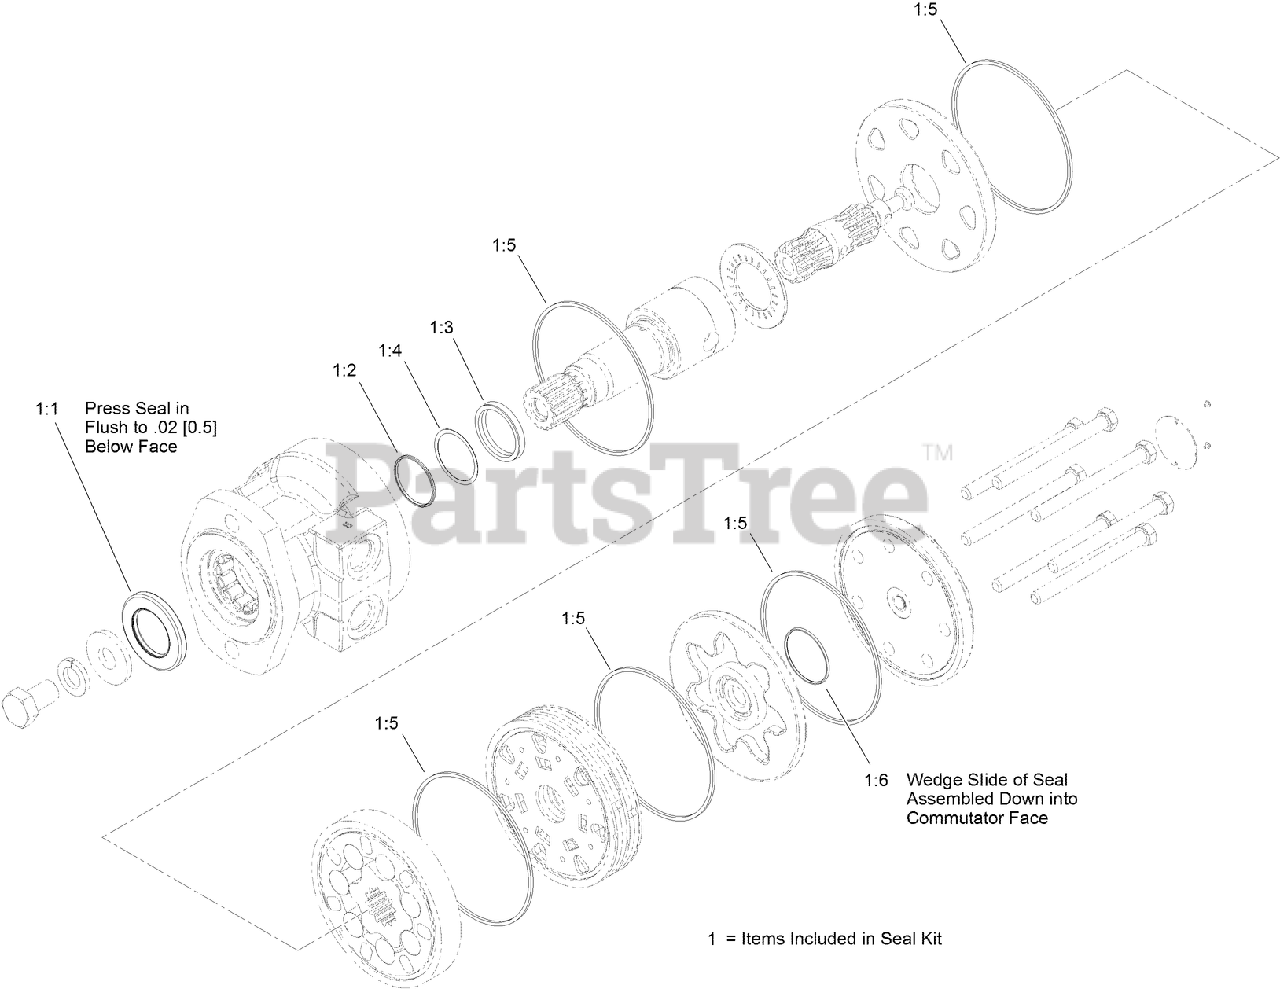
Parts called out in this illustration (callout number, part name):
1	SEAL KIT
1:1	Ring-Back Up
1:2	Washer-Back Up
1:3	SEAL-Shaft
1:4	HUB and BEARING ASM
1:5	HUB and BEARING ASM
1:6	HUB and BEARING ASM
